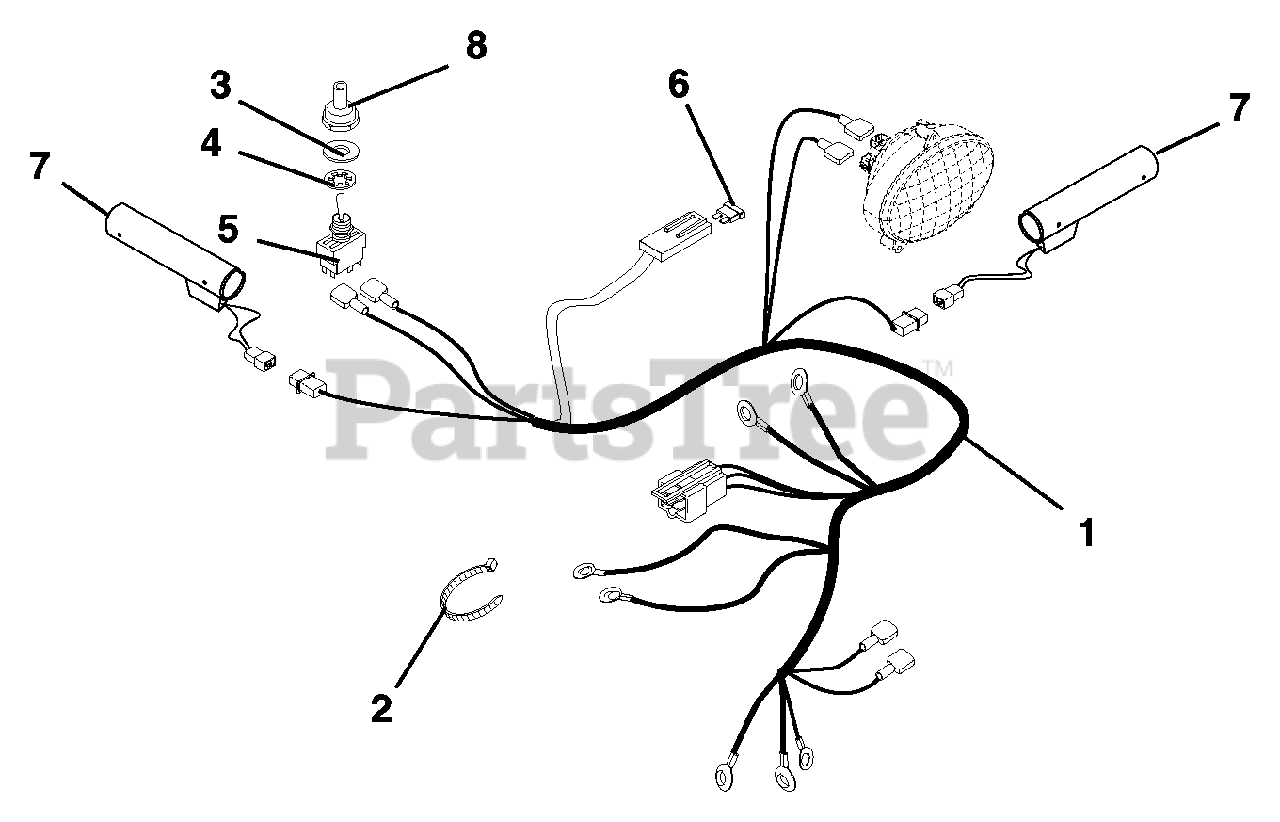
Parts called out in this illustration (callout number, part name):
1	Harness, Wiring-Light and Hand Warmer
2	Cable Tie
3	Washer, Flat Steel .51 x .88 x .024
4	Washer, Locking Internal .56 x .04
5	Switch, On/Off Hand Warmer
6	15 AMP Fuse
7	Hand Warmer with Terminal (Recommend Fast Drying Epoxy for Installation)
8	Boot, Switch
